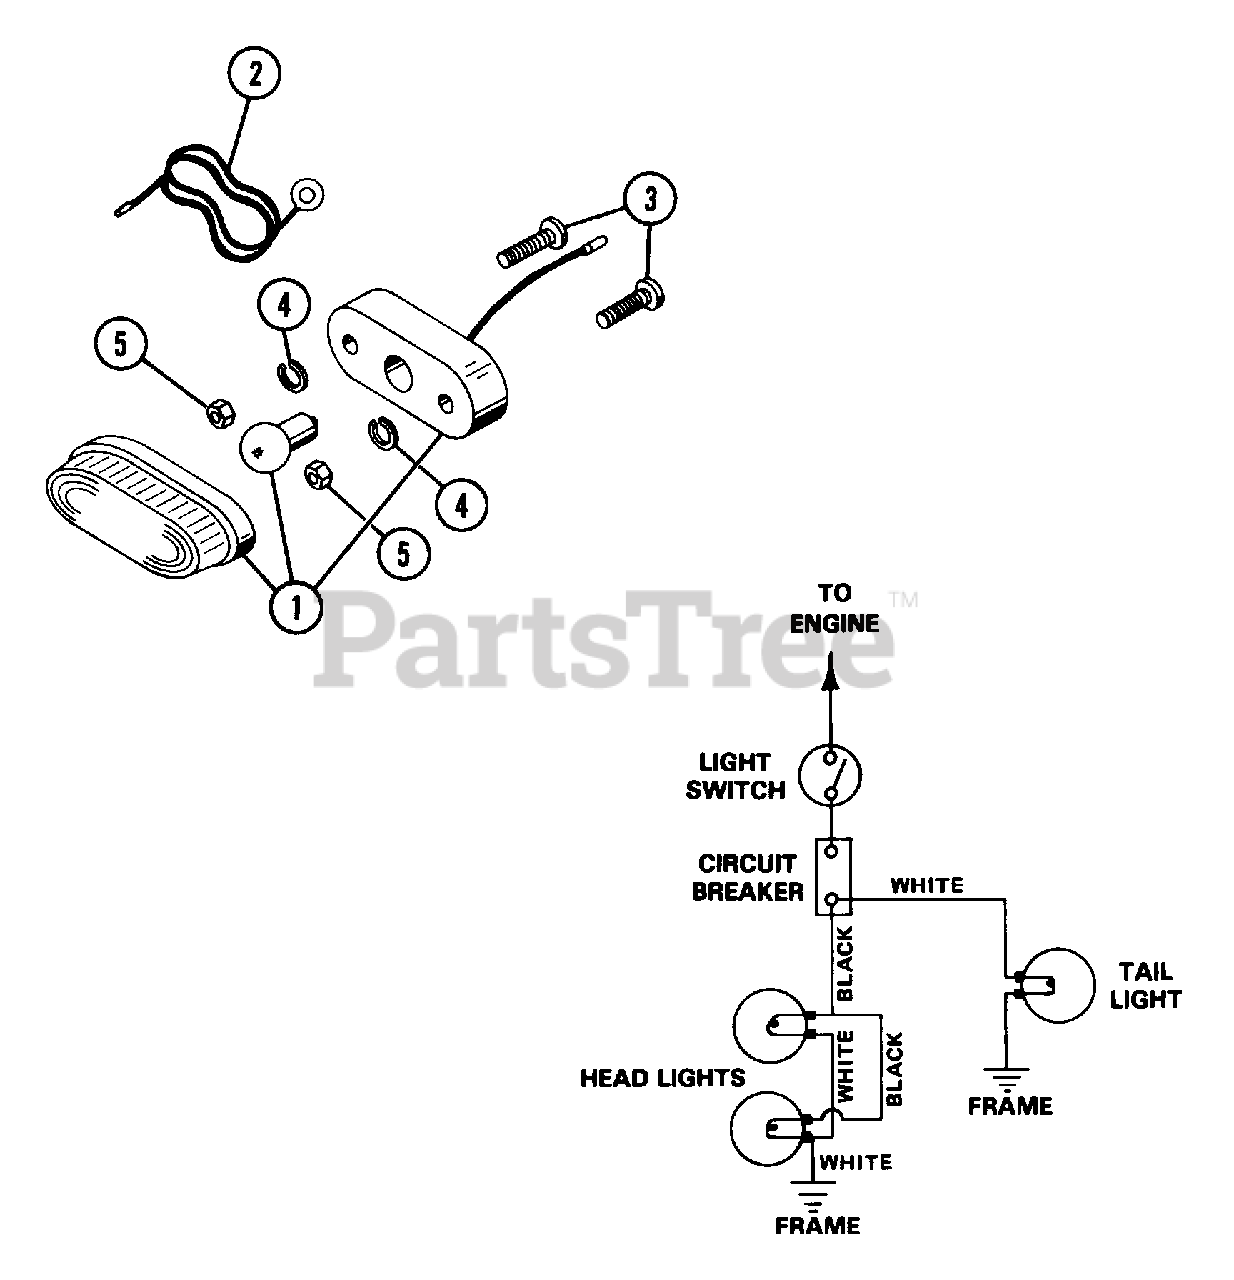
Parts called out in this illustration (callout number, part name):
1	TAIL LIGHT
1	TAIL LIGHT LENS
2	TAIL LIGHT WIRE
3	SCR-MCH 10-24X.50 SLTR PL
4	WSHR-LK 10X.047 MED PL
5	NUT-HEX 10-24 PL
